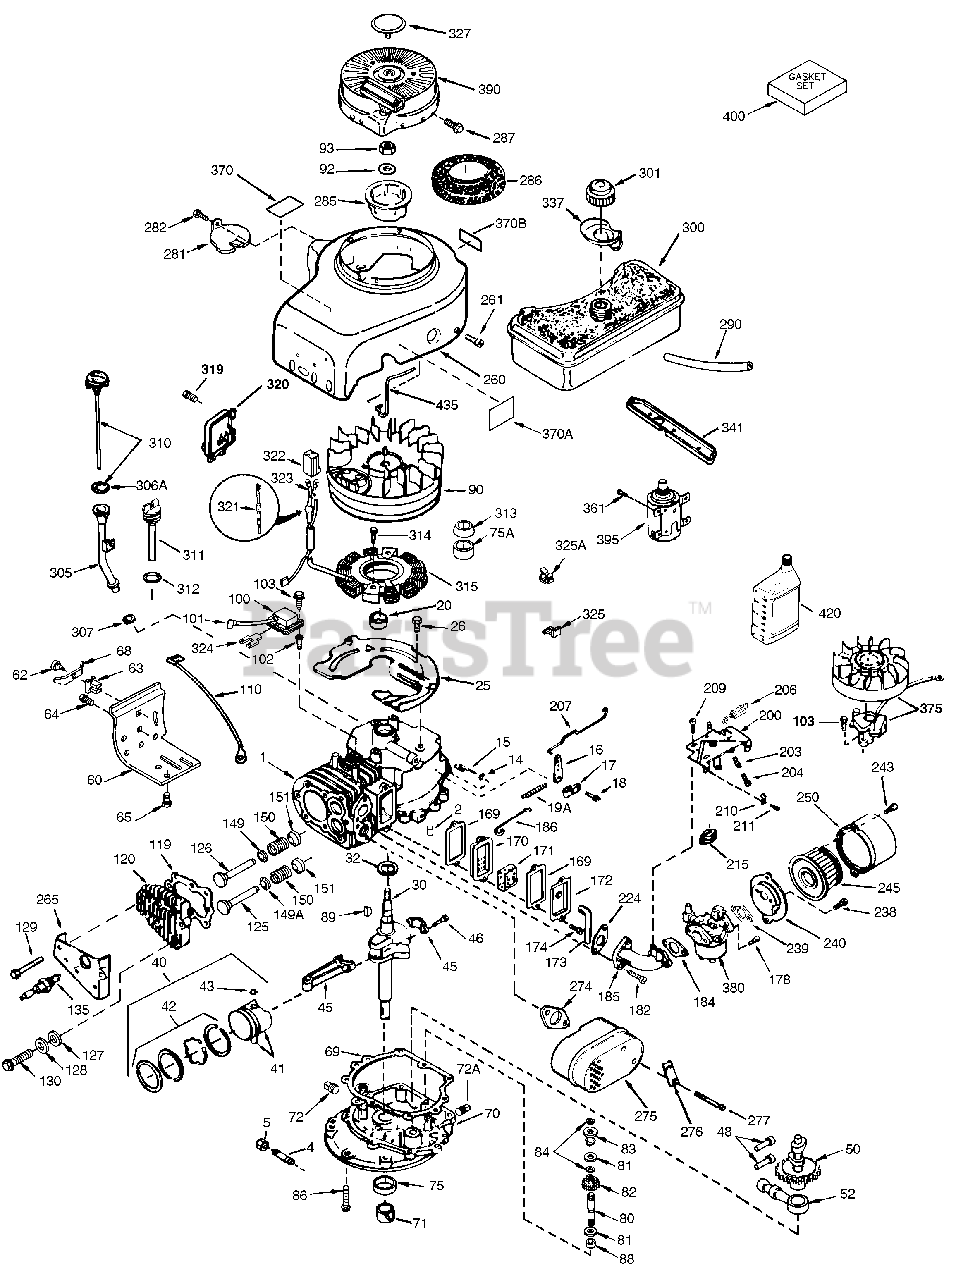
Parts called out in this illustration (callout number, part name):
1	"Cylinder (Incl. 2, 20 & 311)
2	Dowel Pin
14	Flat Washer
15	Governor Rod
16	Governor Lever
17	Governor Lever Clamp
18	Screw, 8-32 x 5/16"
19A	Extension Spring
20	Oil Seal
25	Blower Housing Baffle
26	Screw, 1/4-20 x 5/8"
30	Crankshaft
40	Piston, Pin & Ring Set (Std.)
40	Piston, Pin & Ring Set (.010" OS)
40	Piston, Pin & Ring Set (.020" OS)
41	Piston & Pin Ass'y. (Std.) (Incl. 43)
41	Piston & Pin Ass'y. (.010" OS) Incl. 43
41	Piston & Pin Ass'y. (.020" OS) Incl. 43
42	Ring Set (Std.)
42	Ring Set (.010" OS)
42	Ring Set (.020" OS)
43	Piston Pin Retaining Ring
45	Connecting Rod Ass'y. (Incl. 46)
46	Connecting Rod Bolt (2 Each)
48	Valve Lifter
50	Camshaft (MCR)
52	Oil Pump Ass'y.
60	Blower Housing Extension
64	Screw, T-30, 1/4-20 x 1/2"
65	Screw, 10-24 x 1/2"
69	* Mounting Flange Gasket
70	Mounting Flange Incl. 72, 75, 80 & 8 1
72	Oil Drain Plug (Sq. hd., 1/4-18)
75	Oil Seal
80	Governor Shaft
82	Governor Gear Ass'y. (Incl. 81)
83	Governor Spool
84	Retaining Ring
86	Screw, 1/4-20 x 1-1/4"
88	Spacer (Incl. 81)
89	Flywheel Key
90	Flywheel
92	Lock Washer
93	Flywheel Nut
100	Solid State Ignition
101	Spark Plug Cover
102	Solid State Mounting Stud
103	Screw, Torx T-15, 10-24 x 1"
110	Ground Wire
119	* Cylinder Head Gasket
120	Cylinder Head
125	Exhaust Valve (Std.)(Incl. 151)
125	Exhaust Valve (1/32" OS) (Incl. 151)
126	Intake Valve (Std.) (Incl. 149A)
126	Intake Valve (1/32" OS) (Incl. 149A)
128	Belleville Washer
130	Screw, 5/16-18 x 2-1/2"
135	Resistor Spark Plug (RJ17LM)
149	Valve Spring Cap
149A	Valve Spring Cap
150	Valve Spring
169	Valve Cover Gasket
170	Breather Body
171	Breather Element
172	Valve Cover
173	Breather Tube
174	Screw, 10-24 x 1/2"
178	Screw, 1/4-20 x 27/32"
182	Screw, 5/16-18 x 1-/8"
185	Intake Pipe
186	Governor Link
200	Control Bracket (Incl. 203 & 204)
203	Compression Spring
204	Screw, 5-40 x 7/16"
206	Terminal
207	Choke Link
209	Screw, 10-24 x 9/16"
224	* Intake Pipe Gasket
238	Screw, 10-32 x 1/2"
239	* Air Cleaner Gasket
240	Air Cleaner Body
243	Screw, 8-32 x 3/8"
245	Air Filter (Paper) also available in Packaged Part #740029B
250	Air Cleaner Cover
260	Blower Housing
261	Screw, T-40, 5/16-24 x 21/32"
265	Cylinder Head Cover
274	Muffler Gasket
275	Muffler
276	Locking Plate
277	Screw, 5/16-18 x 2-3/4"
285	Starter Cup
287	Screw, 8-32 x 21/64"
290	Fuel Line (8.62")
300	Fuel Tank (Incl. 301)
301	Fuel Cap (Red 1-1/2" ID) also availab le in Packaged Part #740005B
311	Oil Fill Plug (Incl. 312)
312	Oil Fill Plug Gasket
314	Screw, 1/4-20 x 3/4"
315	Alternator Coil (7 Amp) Incl. 322,322 A & 323
322	Connector Body
322A	Connector Body
323	Terminal
324	Terminal
325	Wire Clip
325A	Wire Clip
327	Starter Plug
370	Lubrication Decal
370A	Logo Decal
370B	Instruction Decal
380	Carburetor (Incl. 184)
390	Rewind Starter
400	Gasket Set (Incl. items marked PK in notes) Incl. part #'s 26756 (1), 272 72A (3),27896A (2),27915A (1),29673 ( 1),30684 (1),31688A (1),32631A (1), 3 3355A (1),35865 (3)
420	SAE 30 4 -Cycle Engine Oil (Quart)
435	Hold Down Clamp
